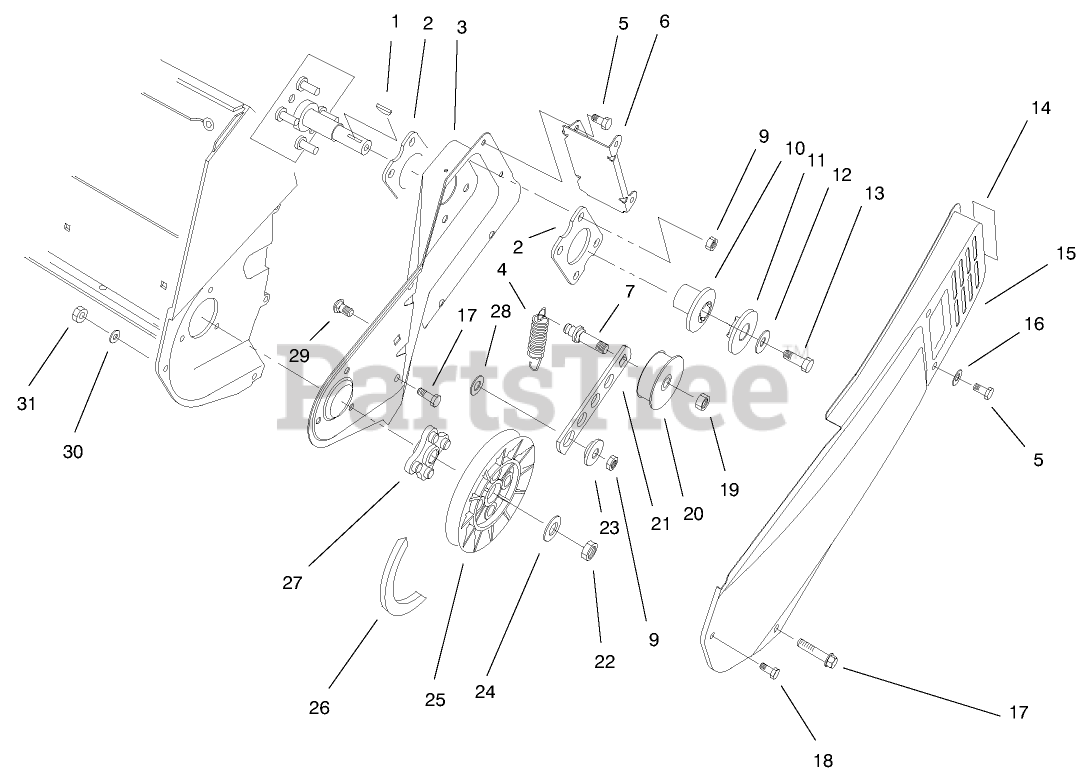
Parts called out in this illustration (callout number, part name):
1	KEY-WOODRUFF
2	PLATE-ENGINE
3	SIDEPLATE-LH
4	SPRING-EXTENSION
5	SCREW-HWH
6	BRACKET-COVER, BELT
7	PIN-IDLER
9	NUT-LOCK, NI
10	HUB-HALF SHEAVE
11	CAP-HALF SHEAVE
12	WASHER-FLAT
13	SCREW-HH
15	COVER-BELT
16	WASHER-FLAT
17	SCREW-PLASTIC
20	PULLEY-IDLER
21	ARM-IDLER
22	NUT-LOCK, NI
23	BUSHING-IDLER
24	WASHER-FLAT
25	PULLEY-DRIVEN
26	V-BELT
28	WASHER
29	SCREW-CARR
30	WASHER-FLAT
31	NUT-LOCK, NI
